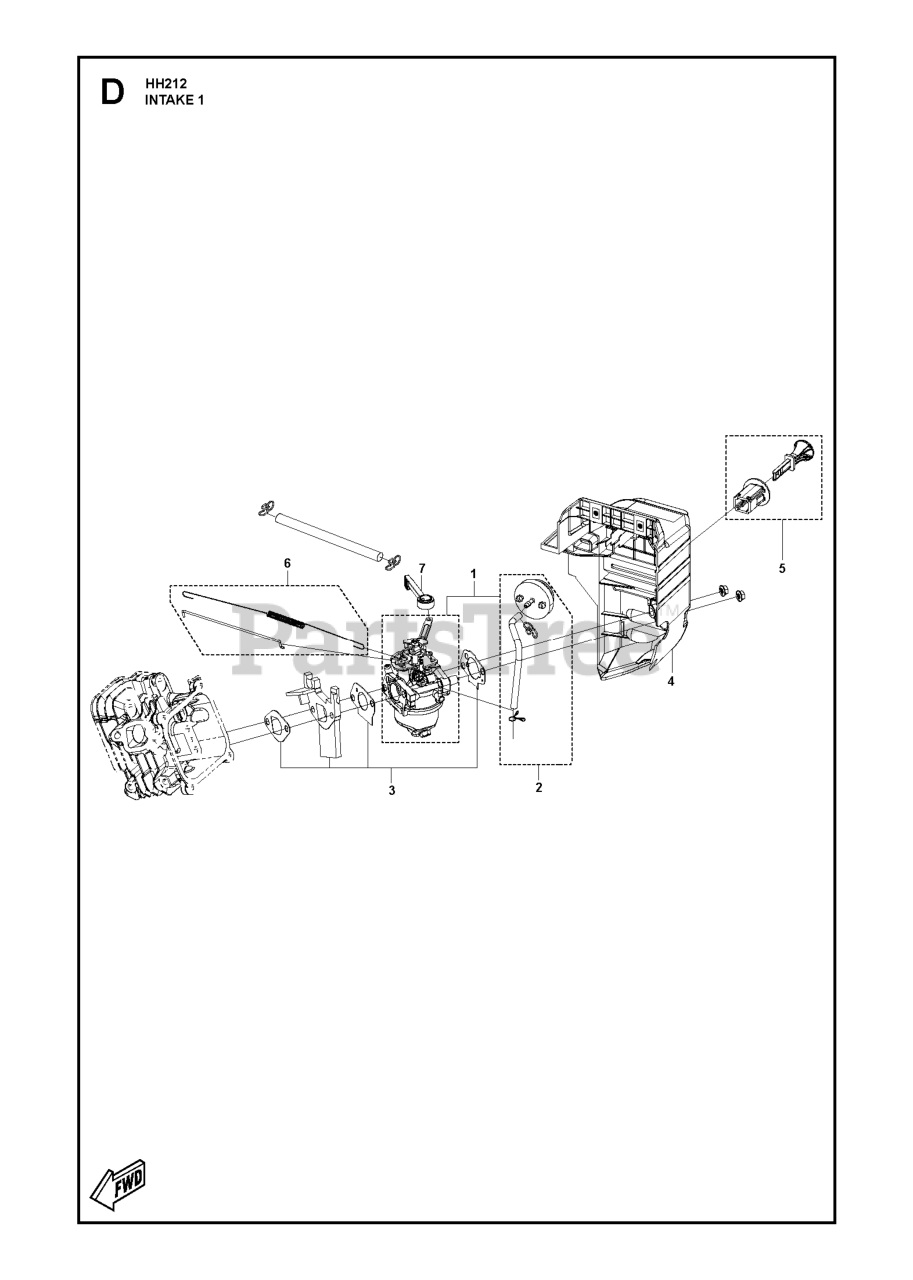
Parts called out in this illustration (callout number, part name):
1	CARBURETOR KIT
3	Carburetors
4	Air Filters
5	KEY ENGINE FGS 100 SERIES SNOW
6	GOVERNOR KIT
